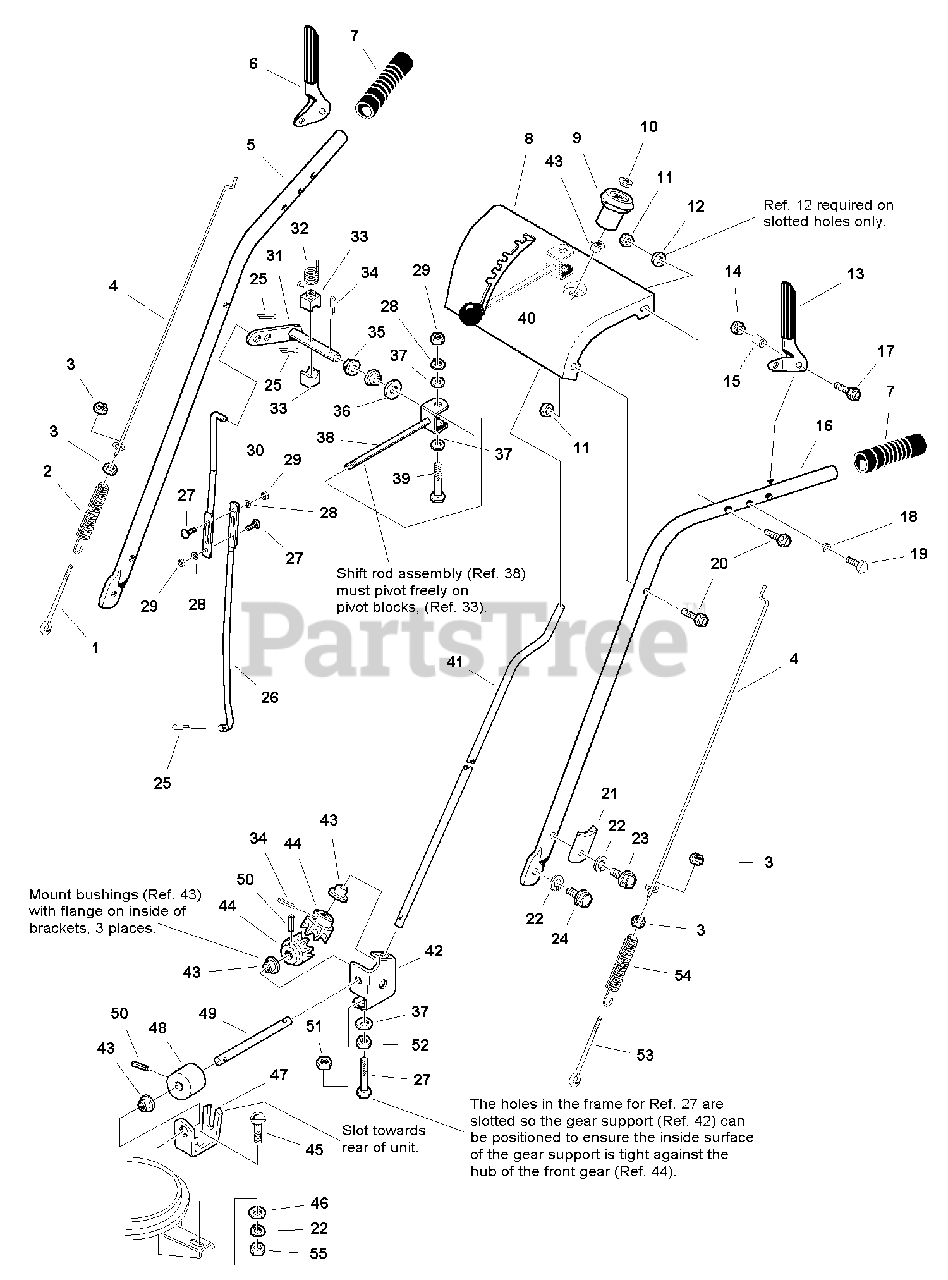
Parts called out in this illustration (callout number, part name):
1	CLUTCH ROD, Lower, RH
2	SPRING, Extension
3	NUT, Hex, #10-24 RH
4	CLUTCH ROD, Traction & Auger Drive
5	HANDLE, RH
6	LEVER, Auger Clutch, RH
7	GRIP, Black Vinyl, for 1" Tube
8	DASHBOARD & SUPPORT ASSEMBLY
9	KNOB, Chute Control Spinner
10	PUSH NUT, 3/8
11	NUT, Hex Lock, 5/16-18
12	WASHER, Flat 5/16
13	LEVER, Traction Drive Clutch, LH
14	NUT, Hex, Centerlock, 1/4-20
15	SPACER, Large
16	HANDLE, LH
17	CAPSCREW, Hex Head, 1/4-20 x 1-1/2
18	SPACER, Small
19	SCREW, Taptite, Pan Head, Torx, 1/4-20 x 3/4
20	CAPSCREW, Hex Head, 5/16-18 x 1-1/2
21	CLAMP, Tube, Saddle
22	LOCKWASHER
23	CAPSCREW, Hex Head, 5/16-18 x 1 3/4
24	CAPSCREW, Hex Head, 5/16-18 x 3/4
25	PIN, Cotter
26	ROD, Shift-Lower
27	CARRIAGE BOLT, 1/4-20 X 5/8
28	LOCKWASHER, 1/4
29	NUT, Hex Head, 1/4-20
30	ROD, Shift-Upper
31	ROD & ARM ASSEMBLY, Pivot
32	SPRING, Torsion
33	BLOCK, Pivot
34	PIN, Cotter
36	WASHER
37	WASHER, Flat 1/4
38	ROD & CLEVIS ASSEMBLY
39	CAPSCREW, Hex Head, 1/4-20 x 2-1/4
40	KNOB, Internal Thread, 3/8-16
41	ROD, Chute Control
42	SUPPORT, Gear
43	BUSHING, Nylon
44	GEAR, Steel, Universal (Supersedes Plastic Gear)
45	CARRIAGE BOLT, 5/16-18 x 3/4
46	WASHER, Flat 5/16
47	BRACKET, Worm Support
48	WORM, Chute
49	ROD, Chute, Worm
50	PIN, Spring
51	NUT, Hex Flange, 1/4-20
52	PUSH NUT, Bolt Retainer 1/4
53	CLUTCH ROD, Lower, LH
54	SPRING, Clutch Rod
55	NUT, Hex, 5/16-18
